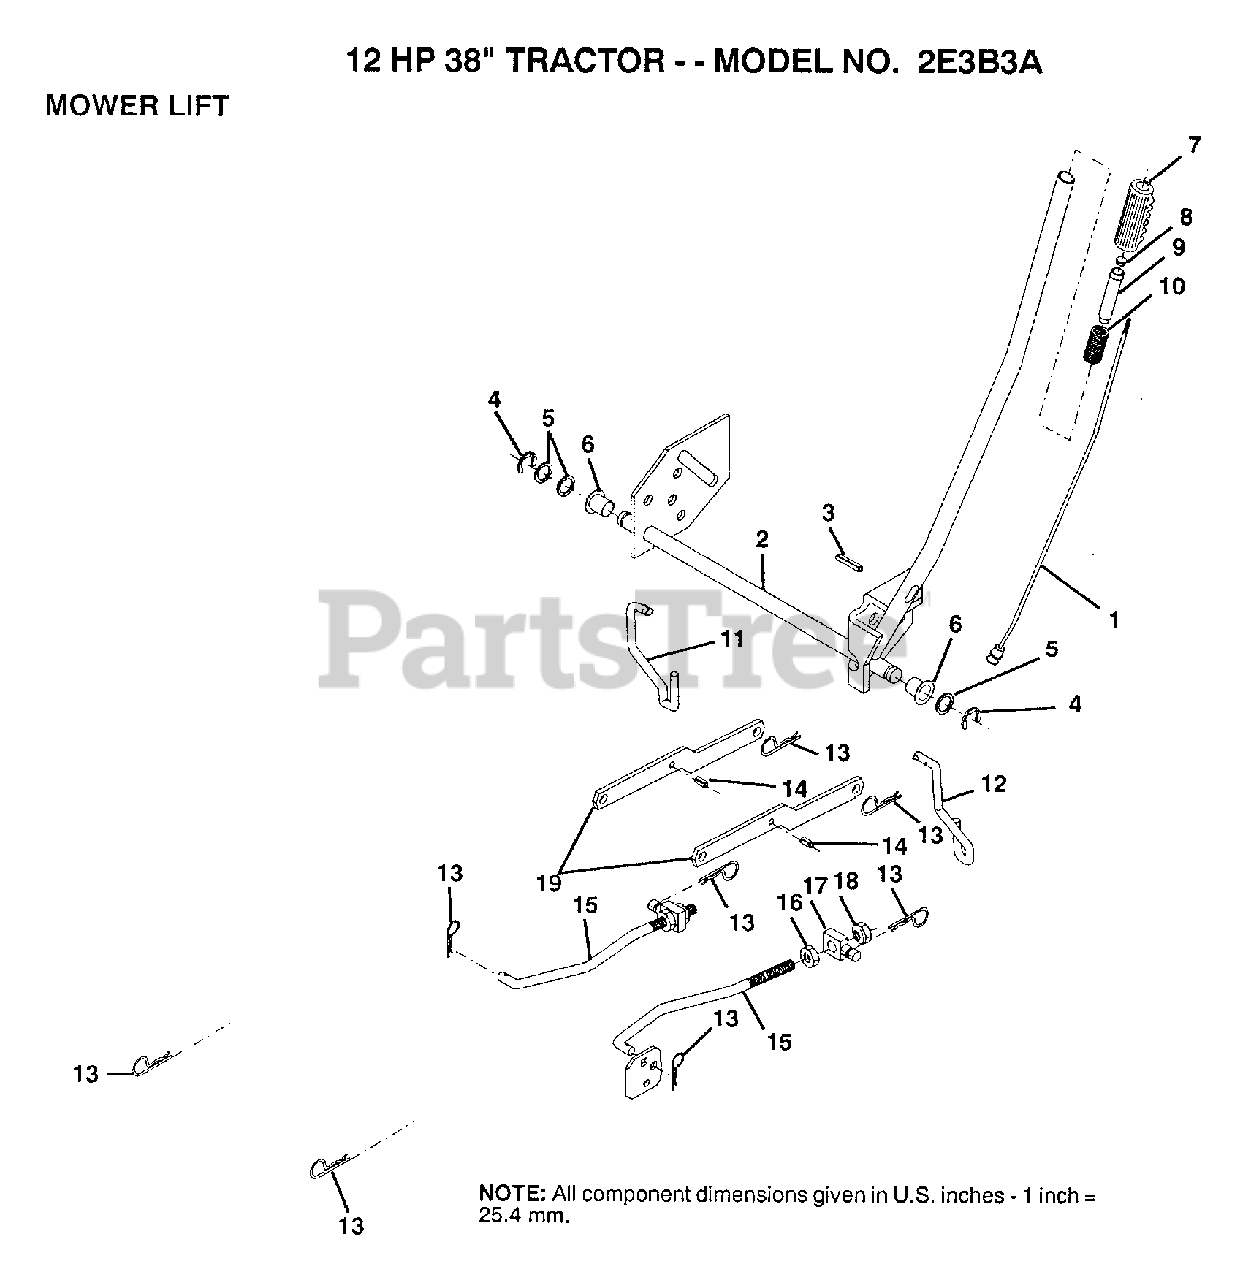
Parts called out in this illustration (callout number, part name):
3	PIN-GROOVE LT
5	WASHER
6	NYLON BEARING
7	GRIP
11	LINK LIFT LH
12	LIFT LINK RH
14	"PIN,SPRING"
15	LINK.FRONT
16	NUT
17	TRUNION
18	NUT.LK.W/WSH.1/2.
